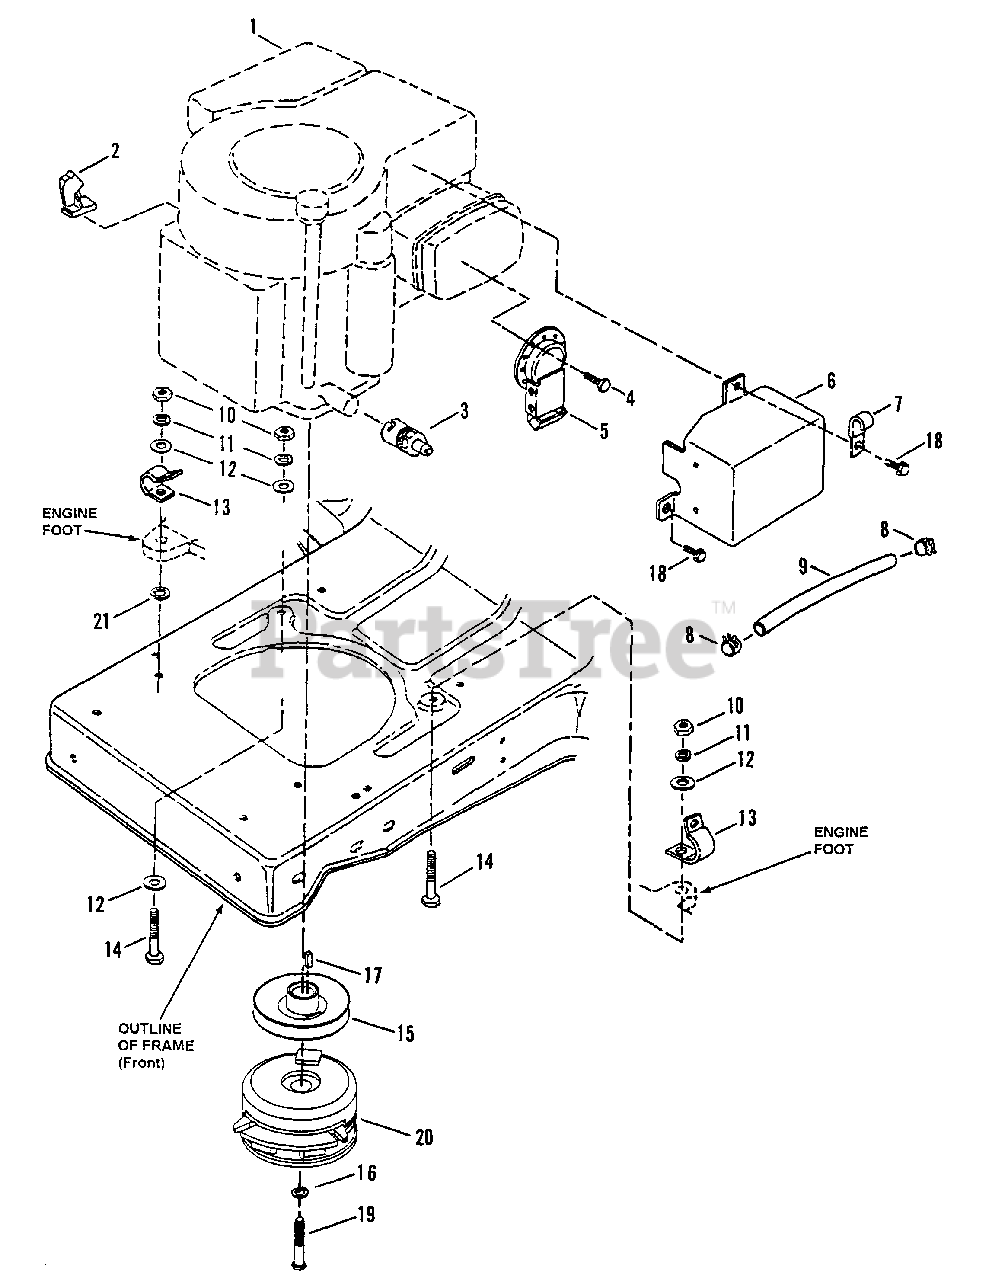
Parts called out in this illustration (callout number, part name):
2	CLIP, Speed
3	ASSEMBLY, Oil Valve
4	SCREW, #8-18 x 1/2" Hex Head, Self-Tapping
5	EXTENSION, Muffler
6	HEAT SHIELD, Muffler
7	CLIP, "J" Type
8	CLAMP, Fuel Line
9	LINE, Fuel, 16" Long
10	NUT, 5/16-18 Hex Grade 5 or B
11	WASHER, 5/16 Split Lock
12	WASHER, 5/16 Flat
13	CLIP, Wiring Harness
14	SCREW, 5/16-18 x 1-3/4" Hex Head Cap Grade 5
15	PULLEY, Traction Drive 4.5" O.D., 1" I.D., 1.85" HUB, 1/4" KW
16	WASHER, 7/16 Split Lock
17	KEY, 1/4 x 1/4 x 3/4" Square
18	BOLT, 1/4-20 x 1/2" Hex Flange Lock Grade 5
19	SCREW, 7/16-20 x 2-1/2" Hex Head Cap Special Grade 5
20	CLUTCH/BRAKE
21	WASHER, 5/16 Internal Tooth Lock
